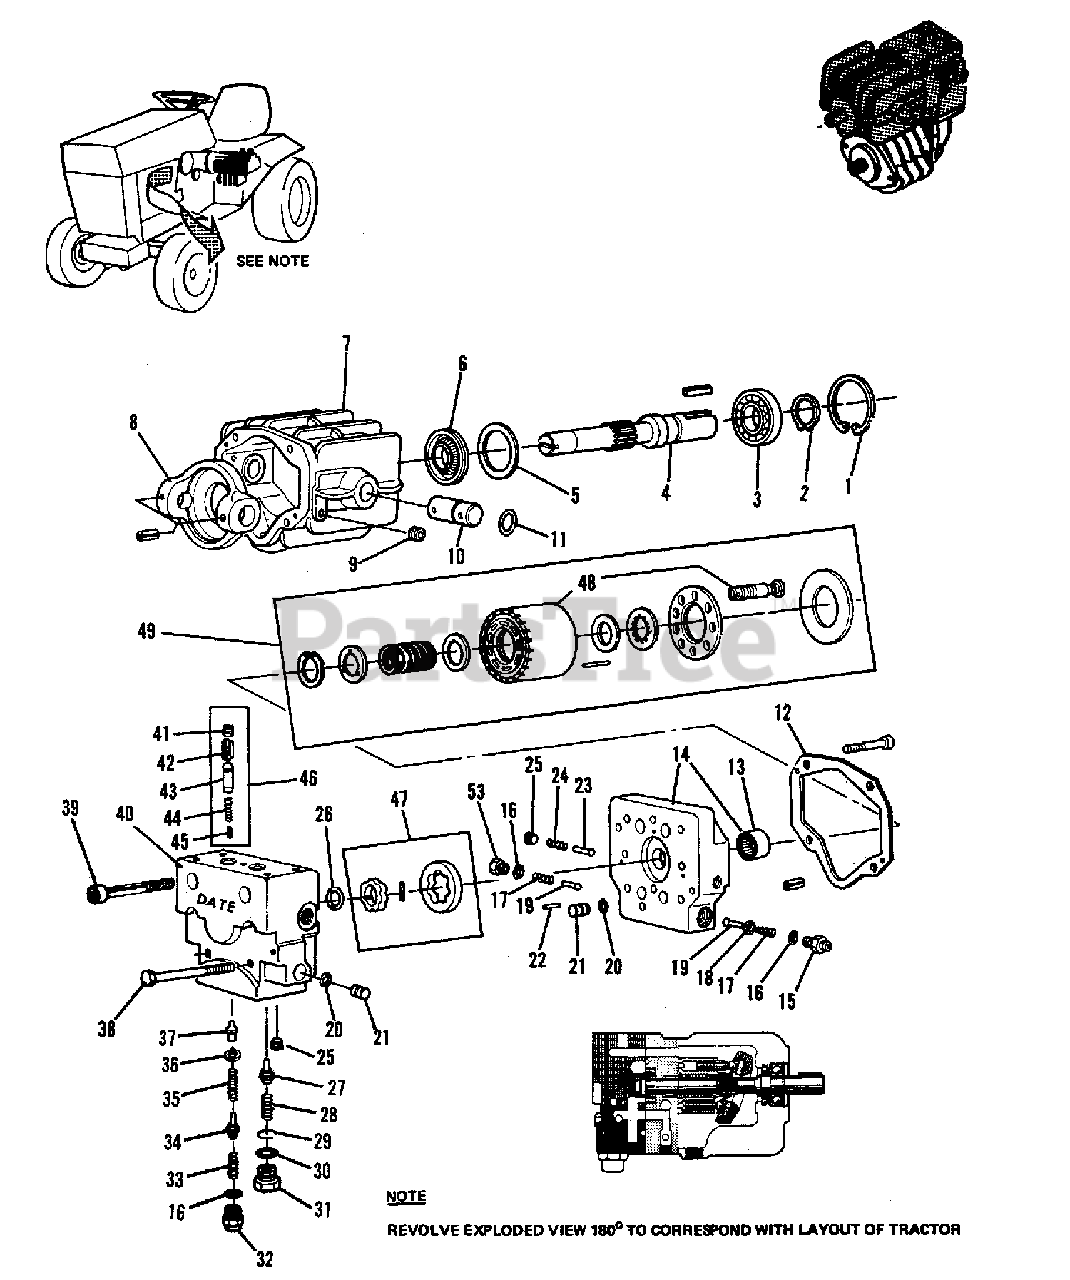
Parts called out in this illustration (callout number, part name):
1	RING, Snap
2	RING, Snap
3	BEARING, Ball
4	SHAFT, Pump
5	SPACER, Bearing
6	SEAL, Shaft
7	HOUSING, Pump
8	PIN, Dowel
10	ROD, Control
12	GASKET, Valve Plate
13	BEARING, Needle
14	PLATE ASSEMBLY, Valve (Includes Item 13)
14	PIN, Dowel
15	CONNECTOR
23	VALVE, Ball Check
29	SHIM (Use As Required)
34	PIN ASSEMBLY
36	SEAT, Spring
37	POPPET ASSEMBLY
40	BLOCK, Transfer
42	GUIDE, Spring
43	VALVE, Check
46	VALVE REPAIR KIT (Includes 41 To 45)
47	GEROTOR Kit, (Includes KEY)
47	KEY, Gerotor
48	CYLINDER KIT (Includes PISTONS)
49	PUMP REPAIR KIT
